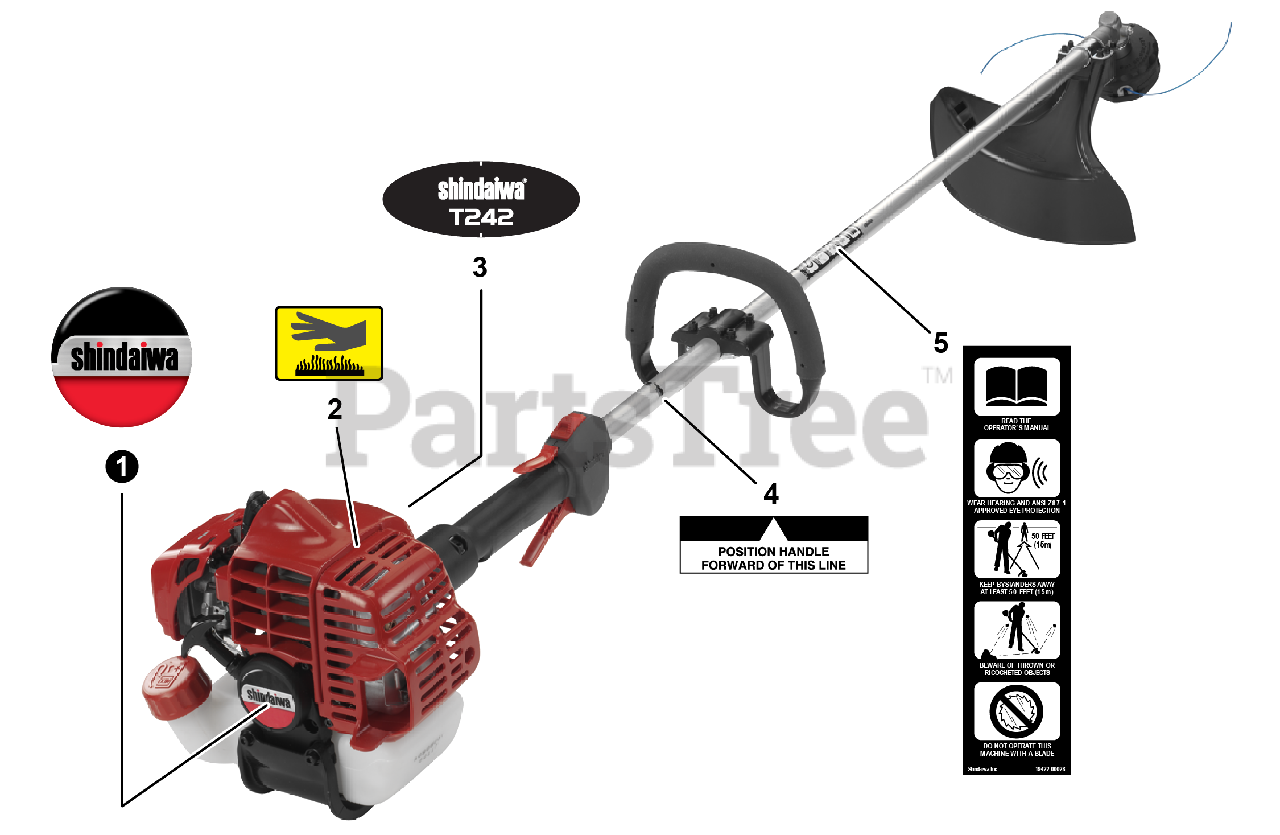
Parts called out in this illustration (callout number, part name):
1	LABEL, RECOIL STARTER
2	LABEL, CAUTION - HOT
3	LABEL - MODEL T242
4	LABEL, HANDLE
5	LABEL, CAUTION
